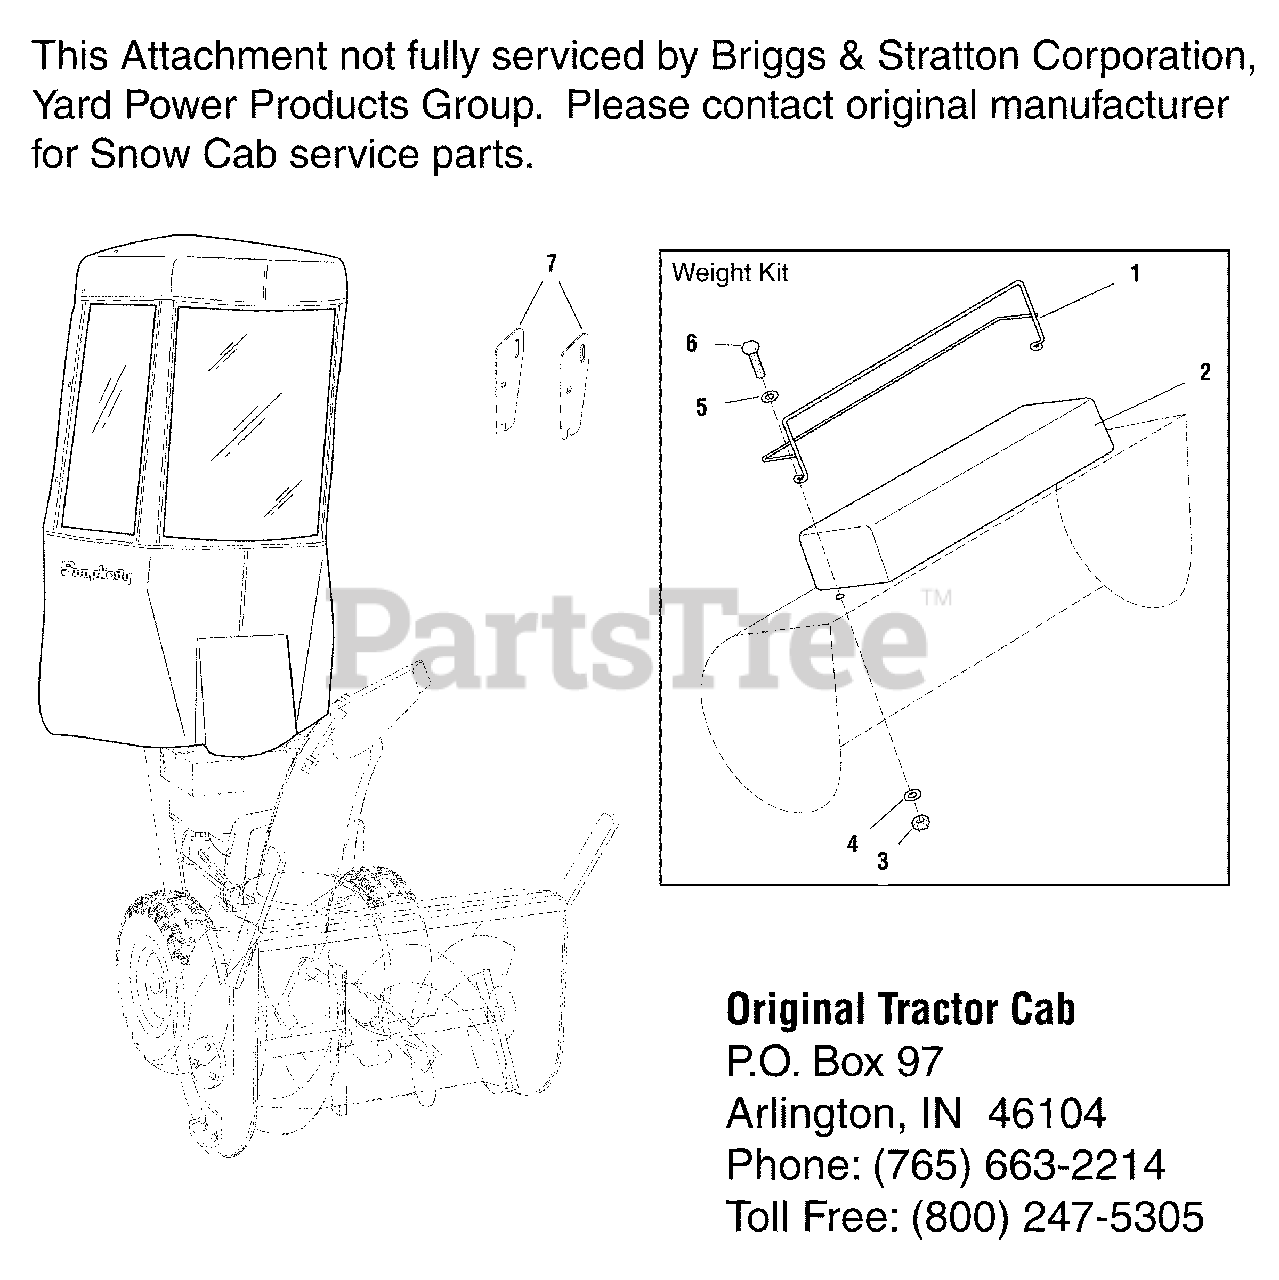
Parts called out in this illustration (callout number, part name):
1	WEIGHT RACK
3	NUT, Hex
4	LOCKWASHER
5	WASHER, Flat
6	CAPSCREW
7	PLATE, Snow Cab Mount
